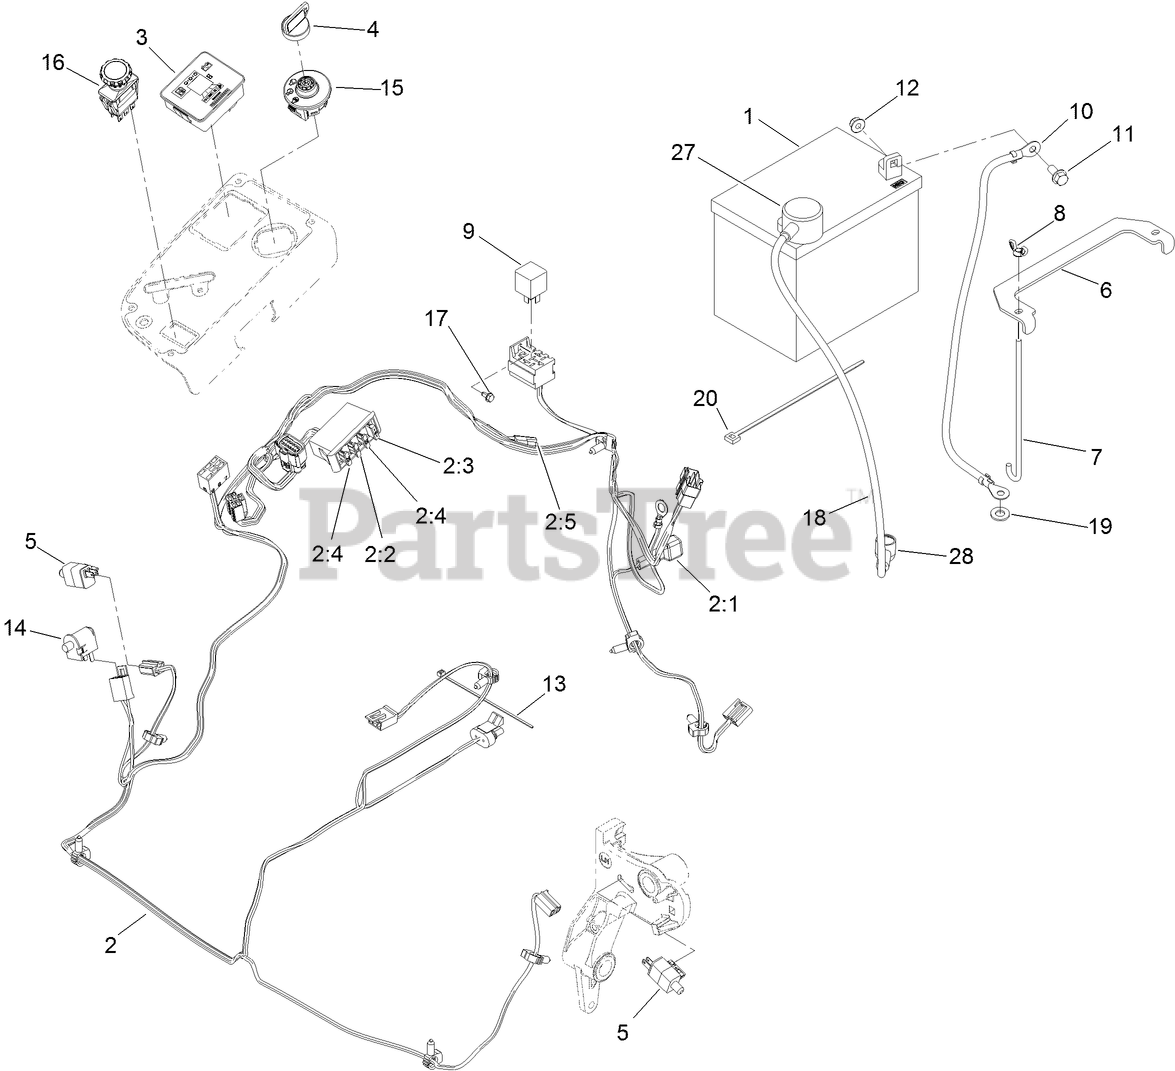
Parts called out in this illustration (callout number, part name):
1	BATTERY-DRY
2	HARNESS-WIRE, MAIN
2:2	FUSE-BLADE, 10 AMP
2:3	FUSE-BLADE, 15 AMP
2:4	FUSE-BLADE, 25 AMP
2:5	CAP-PLUG
3	FUEL/HOUR METER ASM
4	KEY-IGNITION
5	SWITCH
6	STRAP-TIE DOWN, BATTERY
7	BOLT-HOLDDOWN
8	WINGNUT
10	CABLE-BATTERY, NEGATIVE
11	SCREW-HHF
12	NUT-HF, NI
13	TIE-CABLE
14	SWITCH-BAIL
15	SWITCH-IGNITION
16	SWITCH-PTO, 10 AMP
17	SCREW-HWH
18	CABLE-BATTERY, POSITIVE
19	WASHER-FLAT
20	TIE-PLASTIC
27	INSULATOR-BATTERY
28	INSULATOR-SOLENOID
